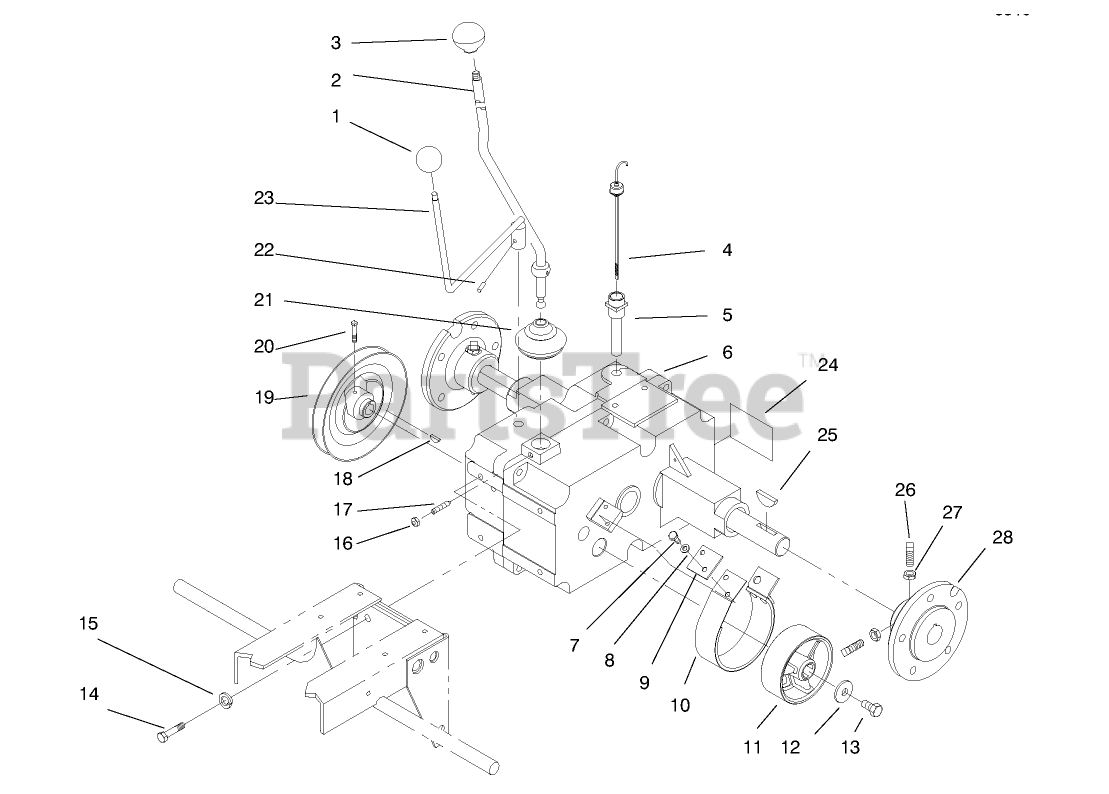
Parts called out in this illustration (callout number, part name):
4	DIPSTICK
6	TRANSMISSION ASM
7	SCREW-HH
8	WASHER-LOCK
10	BRAKE BAND ASM
11	DRUM-BRAKE
12	WASHER
13	SCREW-HEX HD CAP
14	SCREW-HH
15	WASHER-LOCK
16	NUT-HEX
17	SETSCREW
19	PULLEY-TRANSMISSION
20	SCREW-SQH
21	COVER-DUST
22	PIN-SPIROL
23	SHIFT ROD ASM
24	DECAL-UNIDRIVE
25	KEY-WOODRUFF
26	SCREW-SET, SQH
27	NUT-JAM
28	HUB-WHEEL
